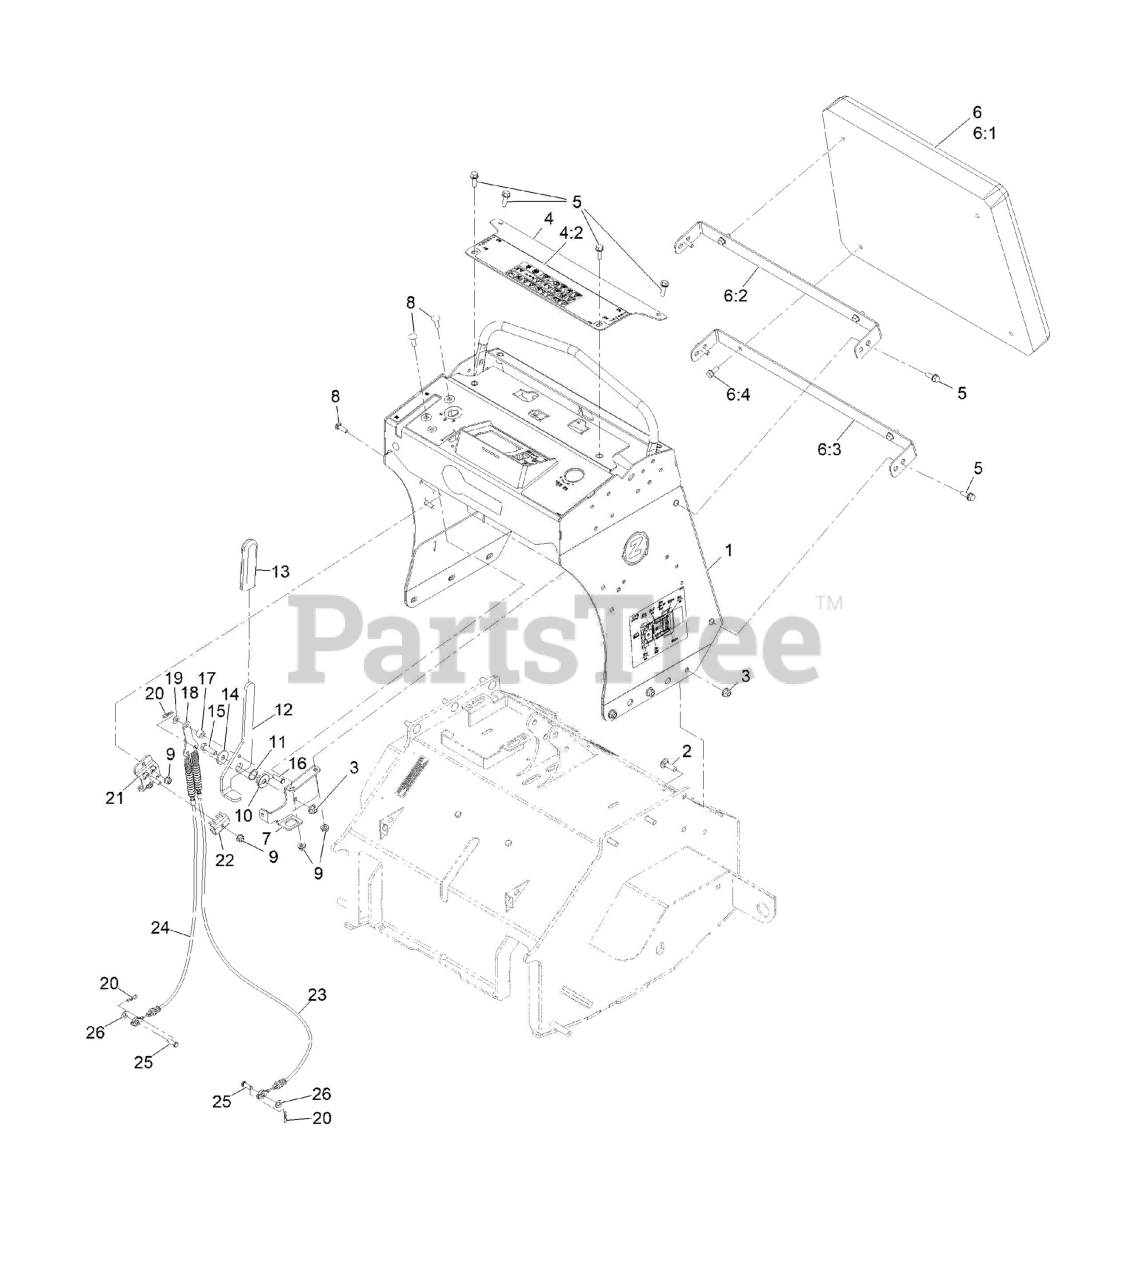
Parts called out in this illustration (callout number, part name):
1	CONTROL TOWER ASM
2	BOLT-CARR
3	NUT-HF, NI
4	CONTROL PANEL ASM
4:2	DECAL-WARNING
5	SCREW-HHF
6	Cushion ASM
6:1	CUSHION-GREY
6:2	BRACKET-PAD, UPPER
6:3	BRACKET-PAD, LOWER
6:4	SCREW-HHF
7	BRACKET-PIVOT, BRAKE
8	SCREW-CARR
9	NUT-HF, NI
10	PIVOT-FLANGE
11	WASHER-WAVE
12	HANDLE-BRAKE
13	GRIP-LEVER
14	WASHER
15	SCREW-HH
16	Pin-Yoke
17	Bushing
18	Yoke-Cable
19	SPACER-NYLON
21	Mount-Cable, Brake
22	Clamp-Cable
23	CABLE-BRAKE, LH
24	CABLE-BRAKE, RH
25	PIN-CLEVIS
26	WASHER-PLAIN
